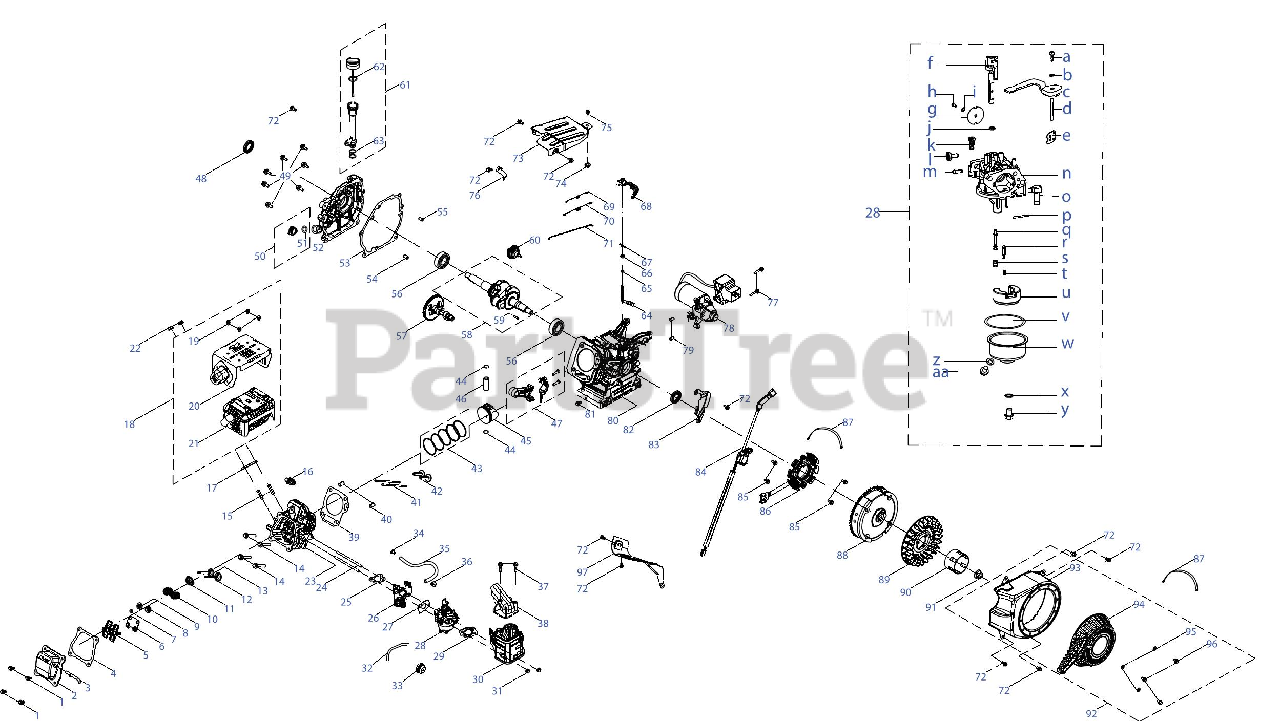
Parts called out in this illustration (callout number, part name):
1	Bolt, M6x16
2	Valve Cover
3	Breather Hose
4	Gasket, Valve Cover
5	Rocker Arm Assembly
6	Rocker Arm Base
7	Valve Adjust Cap, Exhaust
8	Valve Spring Seat
9	Valve Spring Seat
10	Valve Spring
11	Intake Valve Seal
12	Intake Vavle
13	Exhaust Valve
14	Bolt, M8x55
15	Stud, M8x34
16	Spark Plug
17	Gasket, Muffler
18	Muffler
19	Bolt, M5x8
20	Muffler Guard
21	Muffler Body
22	Nut, M8
23	Cylinder Head
24	Stud, M6x110
25	Gasket, Carburetor Insulator
26	Insulator
27	Gasket, Carburetor
28	Carburetor
29	Gasket, Carburetor
30	Air Filter Base
32	Fuel Hose, 3.2x6.5x530
35	Fuel Hose, 6.3x12.5x300
36	Clamp
37	Self-tappling Screw, ST4.2x45
38	Heater Box
39	Gasket, Cylinder Head
40	Pin, 10x16
41	Push Rod
42	Tappet
43	Piston Ring Set
44	Circlip
45	Piston
46	Piston Pin
47	Connecting Rod Assembly
48	Oil Seal, 25x41.25x6
49	Bolt, M8x32
50	Oil Plug
51	O-Ring, 15.8x2.5
52	Crankcase Cover
53	Gasket, Crankcase
54	Pin, 9x14
55	Pin, 7x14
56	Bearing, 6205
57	Camshaft
58	Crankshaft
59	Woodruff Key
60	Governor Gear
61	Dipstick
62	O-Ring, 21x2.77
63	O-Ring, 15.5x1.5
64	Governor Gear Shaft
65	O-Ring, 5.2x1.9
66	Oil Seal, 6x11x4
67	Cotter Pin
68	Governor Lever
69	Governor Spring
70	Idle Spring
71	Throttle Linkage
72	Bolt, M6x12
73	Governor Shield
74	Nut, M6
75	Bolt, M6x28
76	Spring Rack
77	Bolt, M6x32
78	Electric Starter
79	Pin, 8x8
80	Crankcase
81	Earth Bolt
82	Oil Seal, 25x41.25x6
83	Lower Shield
84	Ignition Module
85	Bolt, M6x25
86	Charging Coil
87	Tape, L=150mm
88	Flywheel
89	Cooling Fan
90	Starter Cup
91	Nut, M14x1.5
92	Recoil Starter
93	Blower Housing
94	Recoil Starter
95	Washer, 6
96	Bolt, M6x10
97	Shroud
